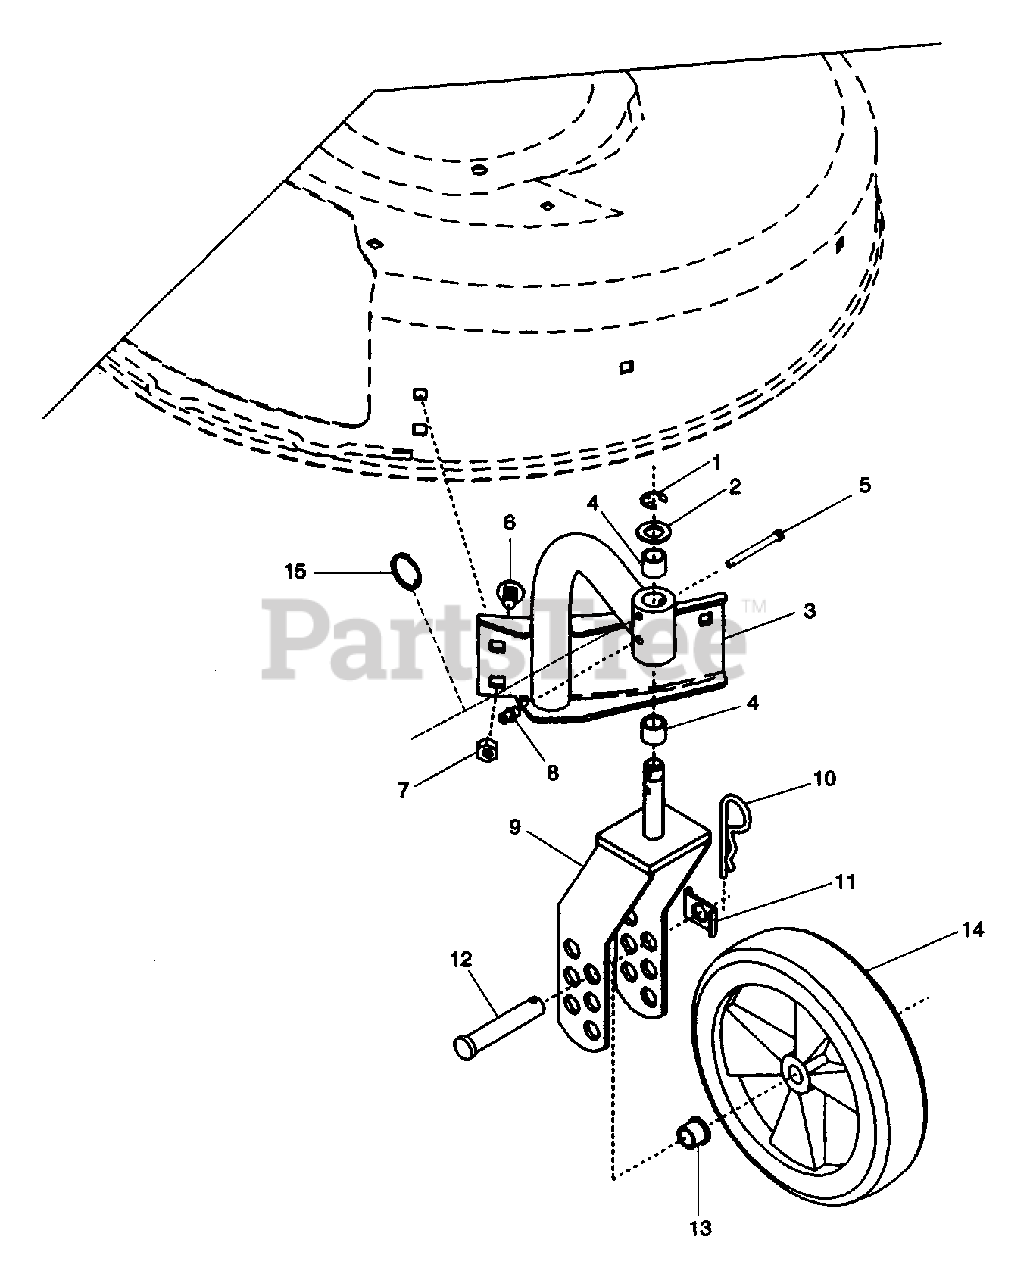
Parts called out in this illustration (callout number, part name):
1	RG-RTNG-EXT .438X.035
2	WSHR-FL-STL .505X.880X.072 PL
3	RIGHT MOUNT ARM WELDMENT
4	BSHG-SLV .500X.625X.500
5	PIN-CLEV .184X1.50 YWZC
6	BLT-RDHDSQSHNK .31-18X.50 YZ
7	NUT-FLG. .312-18 PL
8	FTG-LUBE .25-28X.256 YWZC
9	WHEEL YOKE WELDMENT
10	PIN-HAIR INT .14X.4X2.75
11	AXLE TAB
12	PIN-CLEV .494X2.62 YWZC
13	BSHG-FLG .500X.625X.500X.750
14	WHEEL
15	KICKOUT RING YWZC
